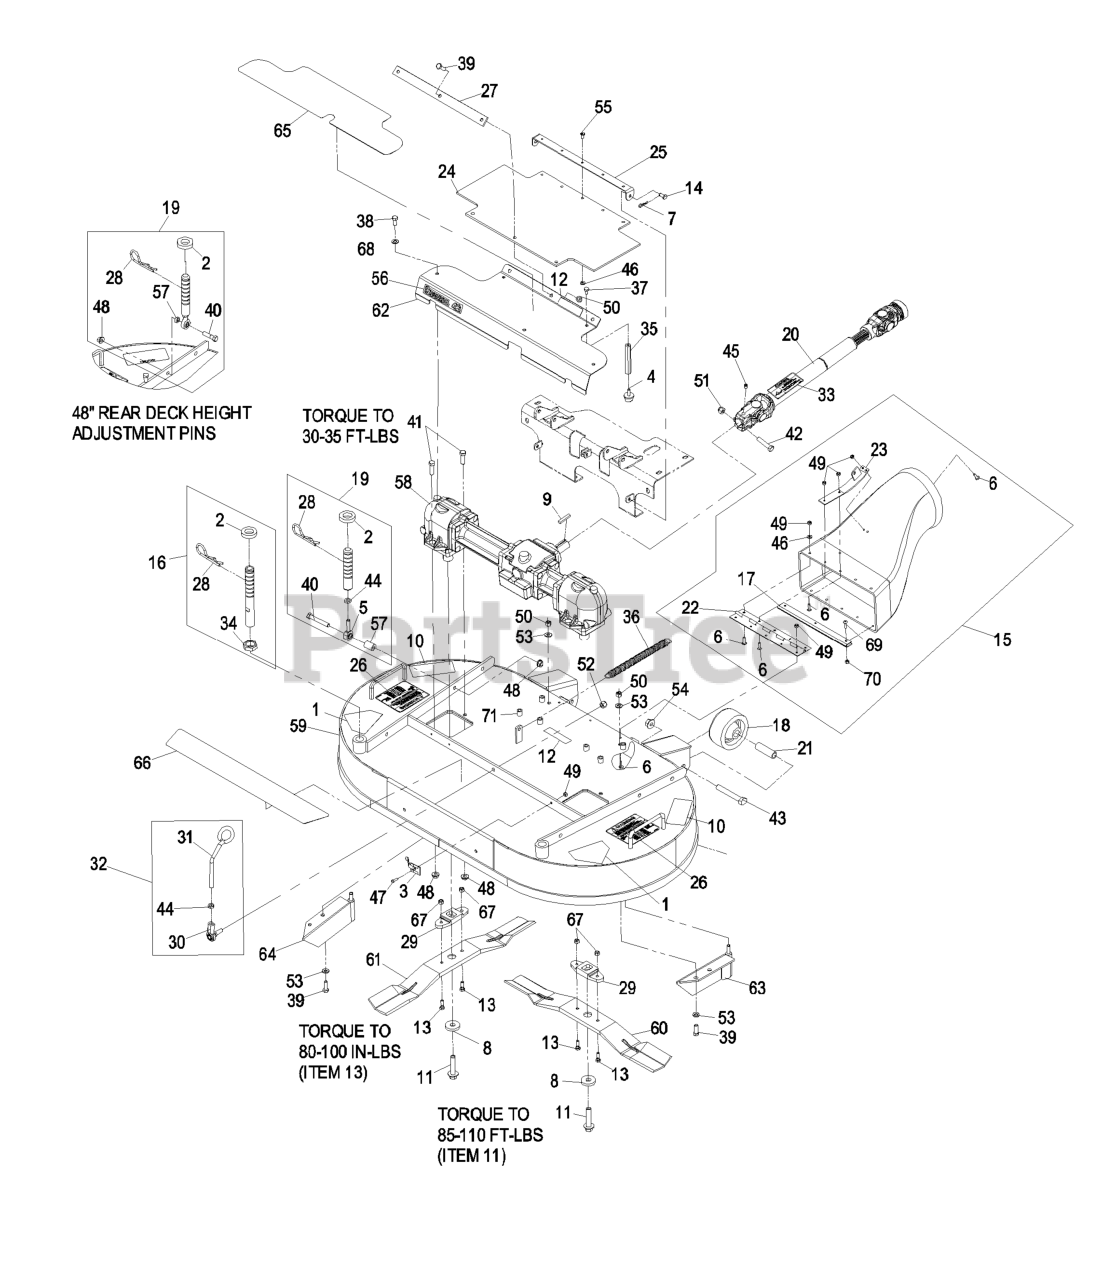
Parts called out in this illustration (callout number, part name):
1	DECAL-DANGER
2	SPACER-DECK SUPPORT
3	CLIP-DECK, HOLD UP ROD
4	BUMPER-RUBBER
5	BALLJOINT
6	SCREW-HEAD, TRUSS
7	PIN-COTTER
9	KEY-SQUARE
10	DECAL-TORQUE
11	BOLT-BLADE
12	DECAL-COVER, MISSING
13	BOLT-SHEAR
14	PIN-CLEVIS
15	DISCHARGE TUBE ASM
16	FRONT DECK HEIGHT ADJUST
17	GUARD-PLENUM
18	ROLLER-DECK
19	REAR DECK HEIGHT ADJUST A
20	DRIVE SHAFT ASM
21	SPACER-ROLLER
22	HINGE-PIANO
23	MOUNT-SPRING
24	GUARD-PTO
25	BRACKET-GUARD, PTO
27	STRAP-DRIVE, LINE COVER
28	PIN-CUT HEIGHT
29	DRIVER-BLADE
30	BALLJOINT-RH
31	LATCH-DECK
32	DECK LATCH ASM
33	DECAL-DRIVELINE
34	NUT-JAM
35	STAND-OFF
36	SPRING-EXTENSION
37	SCREW-HH
38	SCREW-HH
39	SCREW-HH
40	SCREW-HH
41	SCREW-HH
42	SCREW-HH
43	SCREW-HH
44	NUT-HEX
45	SCREW-SET, HSH
46	WASHER-FLAT
48	NUT-HHF, WHIZ
49	NUT-LOCK, NI
50	NUT-LOCK, NI
51	NUT-LOCK, NI
52	NUT-LOCK
53	WASHER-SPRING
54	NUT-HHF
55	RIVET-BLIND
56	DECAL,COMMERCIAL 42
57	TUBE-INTERLOCK
58	GEARBOX ASM
59	DECK ASM
60	BLADE,22 INCH LH
61	BLADE,22 INCH RH
62	ASM,GEARBOX COVER 42 W/DE
63	BAFFLE-LH
64	BAFFLE-RH
65	PAD-ANTI SKID
66	PAD-SKID, ANTI
67	NUT-LOCK, NI
68	WASHER-PLAIN
69	BOLT-CARR
70	NUT-LOCK, NI
71	NUT-CLINCH
